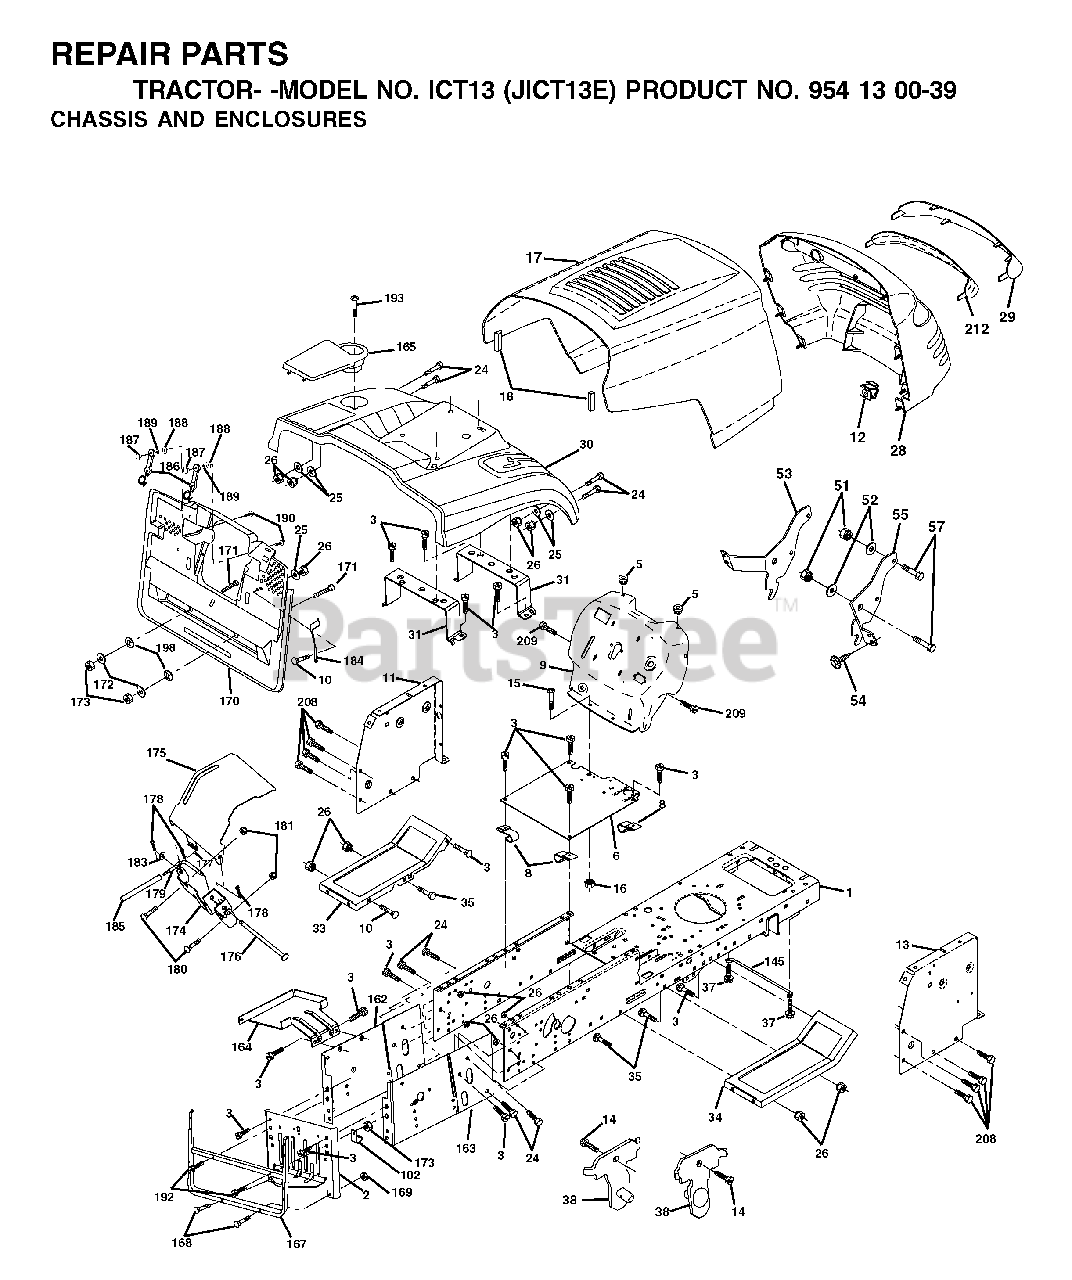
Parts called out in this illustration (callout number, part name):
1	CHASSIS STAMPING
3	SCREW 3/8-16X3/4
5	BUMPER.RUBBER.HOOD
6	SADDLE FLAT
8	CLIP,INSULATOR
10	BOLT D
11	PANEL DASH LH
13	DASH PANEL RH
16	NUT
18	BUMPER HOOD T
20	PLATE MTG
25	WASHER
26	NUT
31	BRACKET SUPPORT FENDER
38	BRACKET.ASM.PIVOT.MOWER.REAR
51	LOCKNUT
57	BOLT
102	CLIP T
145	ROD PIVOT CHASSIS/HOOD
164	SUPPORT
168	BOLT.ROUND.HEAD.SQUARE.NECK
169	NUT T
170	BACKPLATE ASM
171	BOLT
172	WASHER
176	HINGE PIN
177	SPRING COVER LH
178	COTTER PIN
179	ROD PIVOT
181	NUT.CROWNLOCK.1/4
185	TUBE LEVER
186	LATCH ASSY
187	WELDNUT
189	LOCKWASHER
192	SCREW LT
193	SCREW, TRUSS 1/4-20 X 3/4"
207	SCREW, 5/16-18 X 1/2
208	SCREW 3/8-16X1/2
209	SCREW, 3/8-16X3/4
